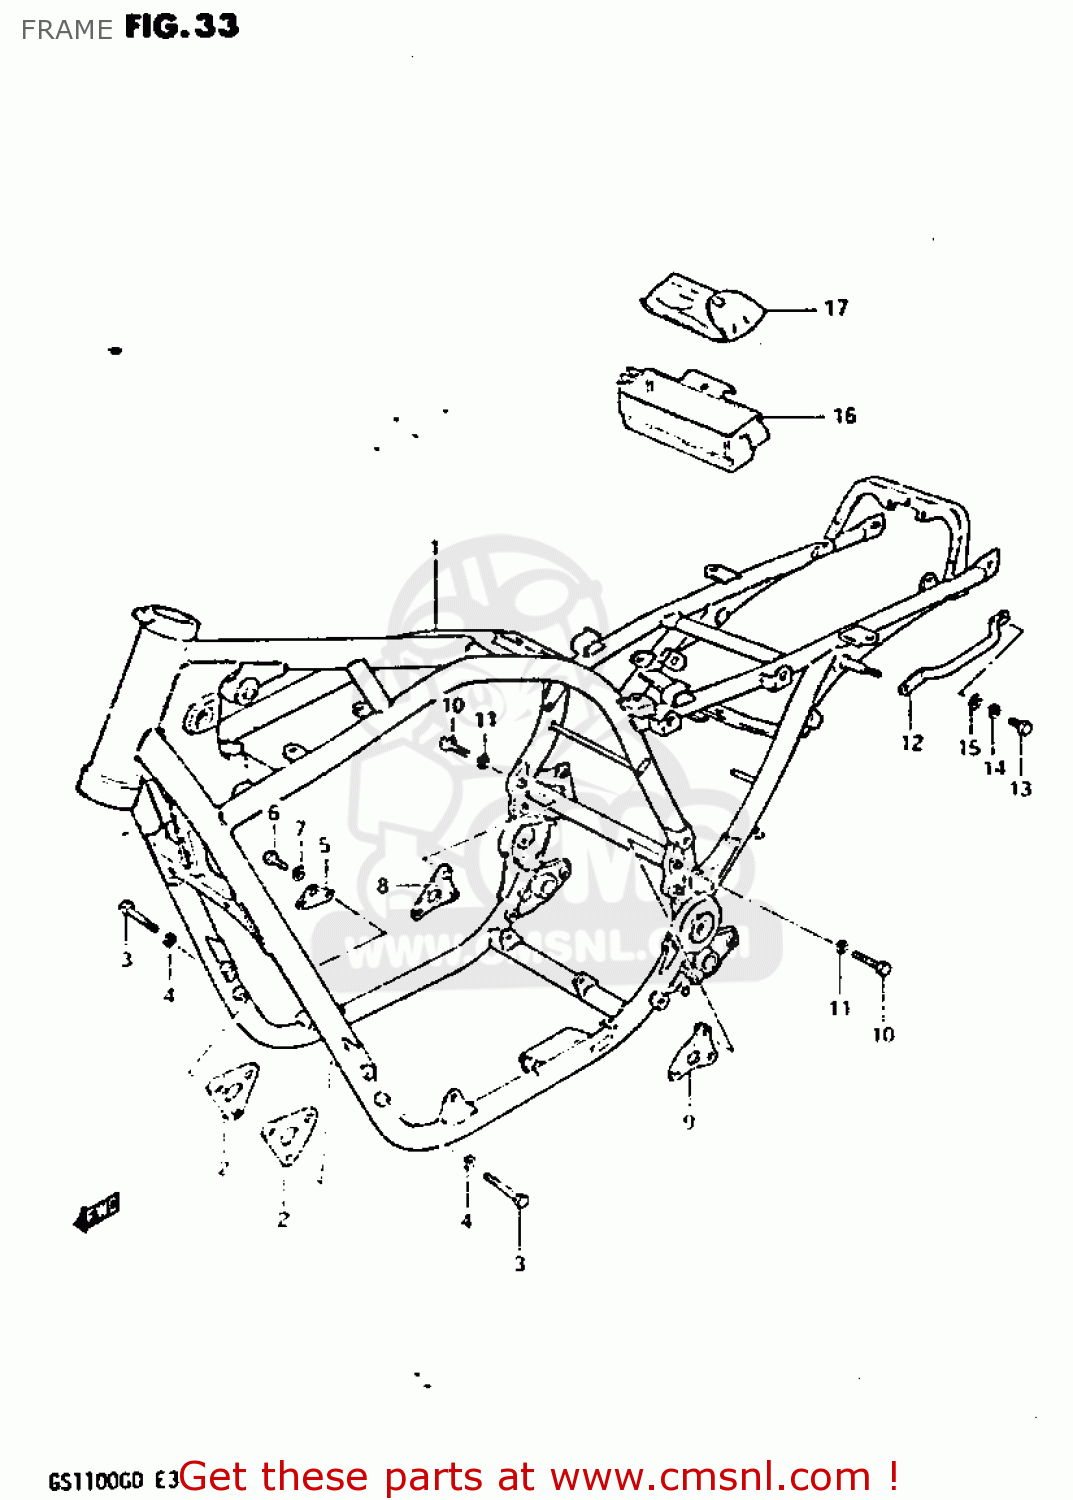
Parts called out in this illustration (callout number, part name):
1	FRAME
2	PLATE,ENGINE MOUNTING
3	BOLT
4	LOCK WASHER
5	PLATE,ENGINE MOUNTING
6	BOLT
7	LOCK WASHER
8	PLATE,ENGINE MOUNTING
9	PLATE,ENGINE MOUNTING
10	BOLT 8X40
11	LOCK WASHER
12	GRIP,FRAME HANDLE
13	BOLT
14	LOCK WASHER
15	WASHER
16	HOLDER,TOOL
17	TOOL SET
